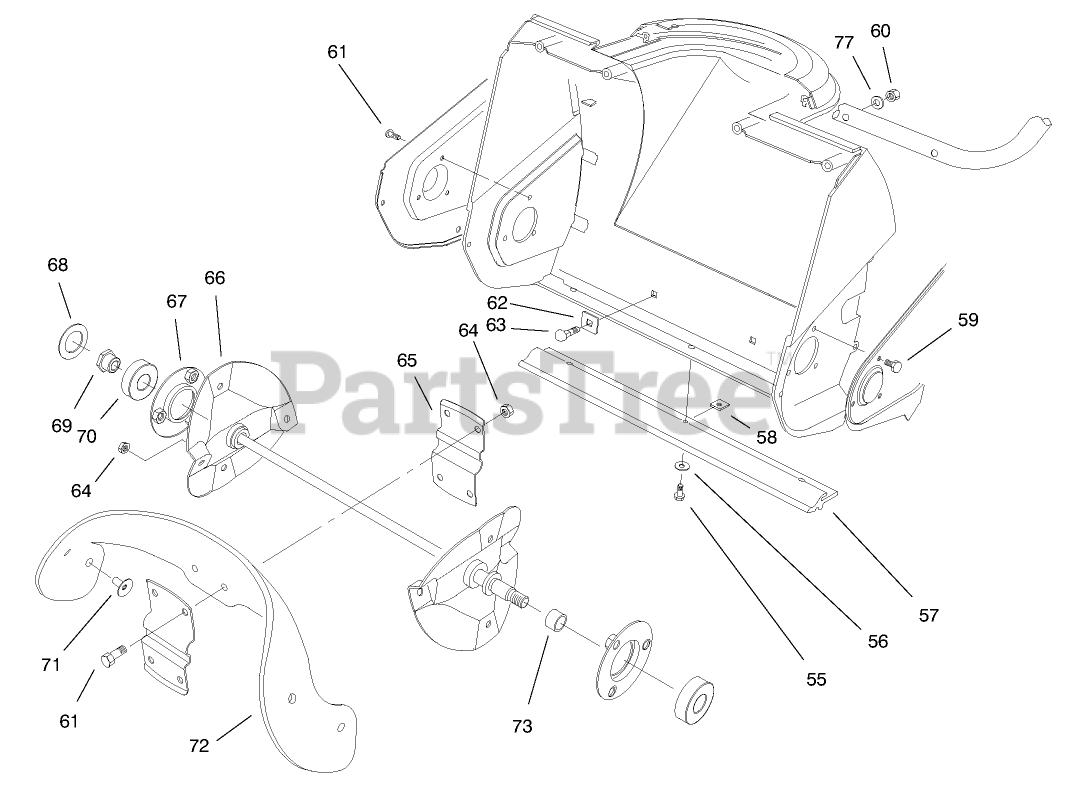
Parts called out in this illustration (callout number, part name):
55	SCREW-HWHTF
56	WASHER-FLAT
57	SCRAPER
58	NUT-CLIP, U
59	SCREW-HH
60	NUT-LOCK, NI
61	SCREW-HHF
62	WASHER-SQUARE
63	SCREW-CARR
64	NUT-LOCK, NI
68	WASHER-RUBBER
70	BEARING-BALL
71	SCREW
72	BLADE-ROTOR
73	SPACER
77	WASHER
